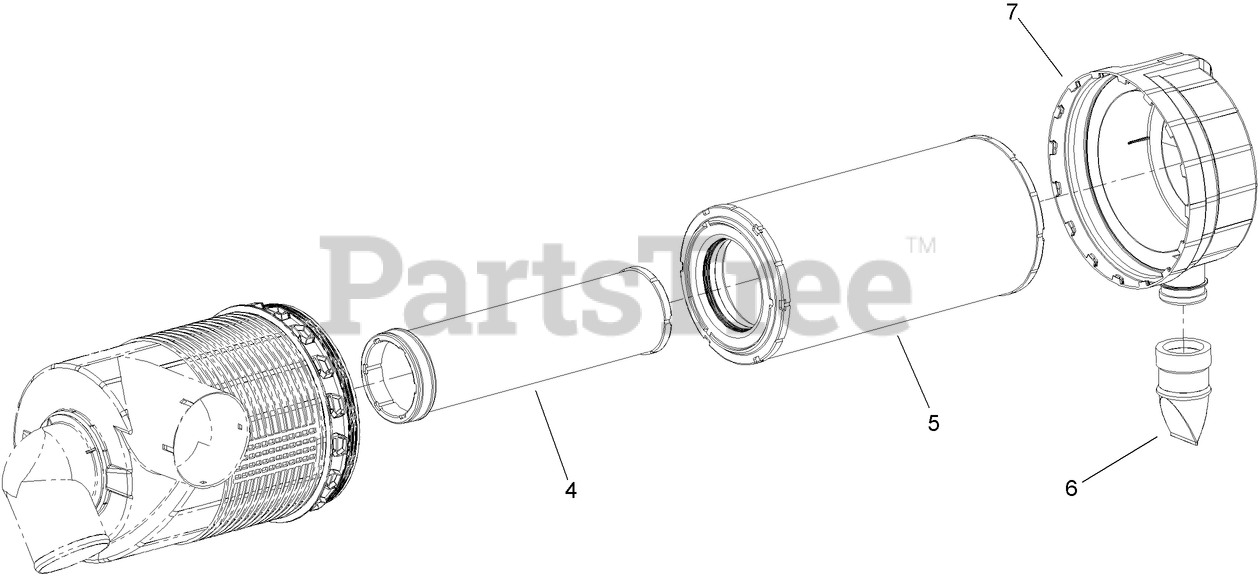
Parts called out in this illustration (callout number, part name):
4	FILTER-AIR, ENGINE (SAFETY)
5	FILTER-AIR, ENGINE (PRIMARY)
6	VALVE-VACUATOR
7	COVER ASM
